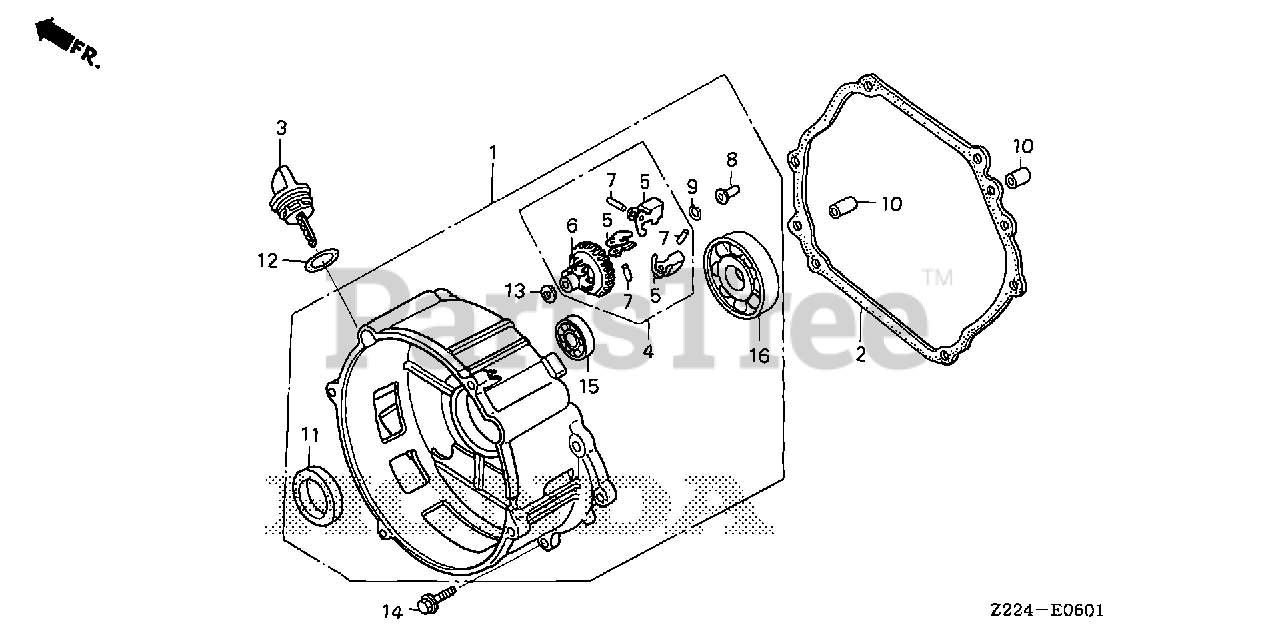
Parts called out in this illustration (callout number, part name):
1	COVER ASSY., CRANKCASE (E-TYPE)
2	GASKET, CASE COVER
2	GASKET, CASE COVER (NINGBO SIL GASKET)
3	CAP, OIL FILLER
4	GOVERNOR ASSY.
5	WEIGHT, GOVERNOR
6	HOLDER, GOVERNOR WEIGHT
7	PIN, GOVERNOR WEIGHT
8	SLIDER, GOVERNOR
9	CLIP, GOVERNOR HOLDER
10	PIN, DOWEL (8X12)
11	OIL SEAL (35X52X8)
12	O-RING (26X2.7)
13	WASHER, PLAIN (6MM)
14	BOLT, FLANGE (8X40)
15	BEARING, RADIAL BALL (6202)
16	BEARING, RADIAL BALL (6207)
